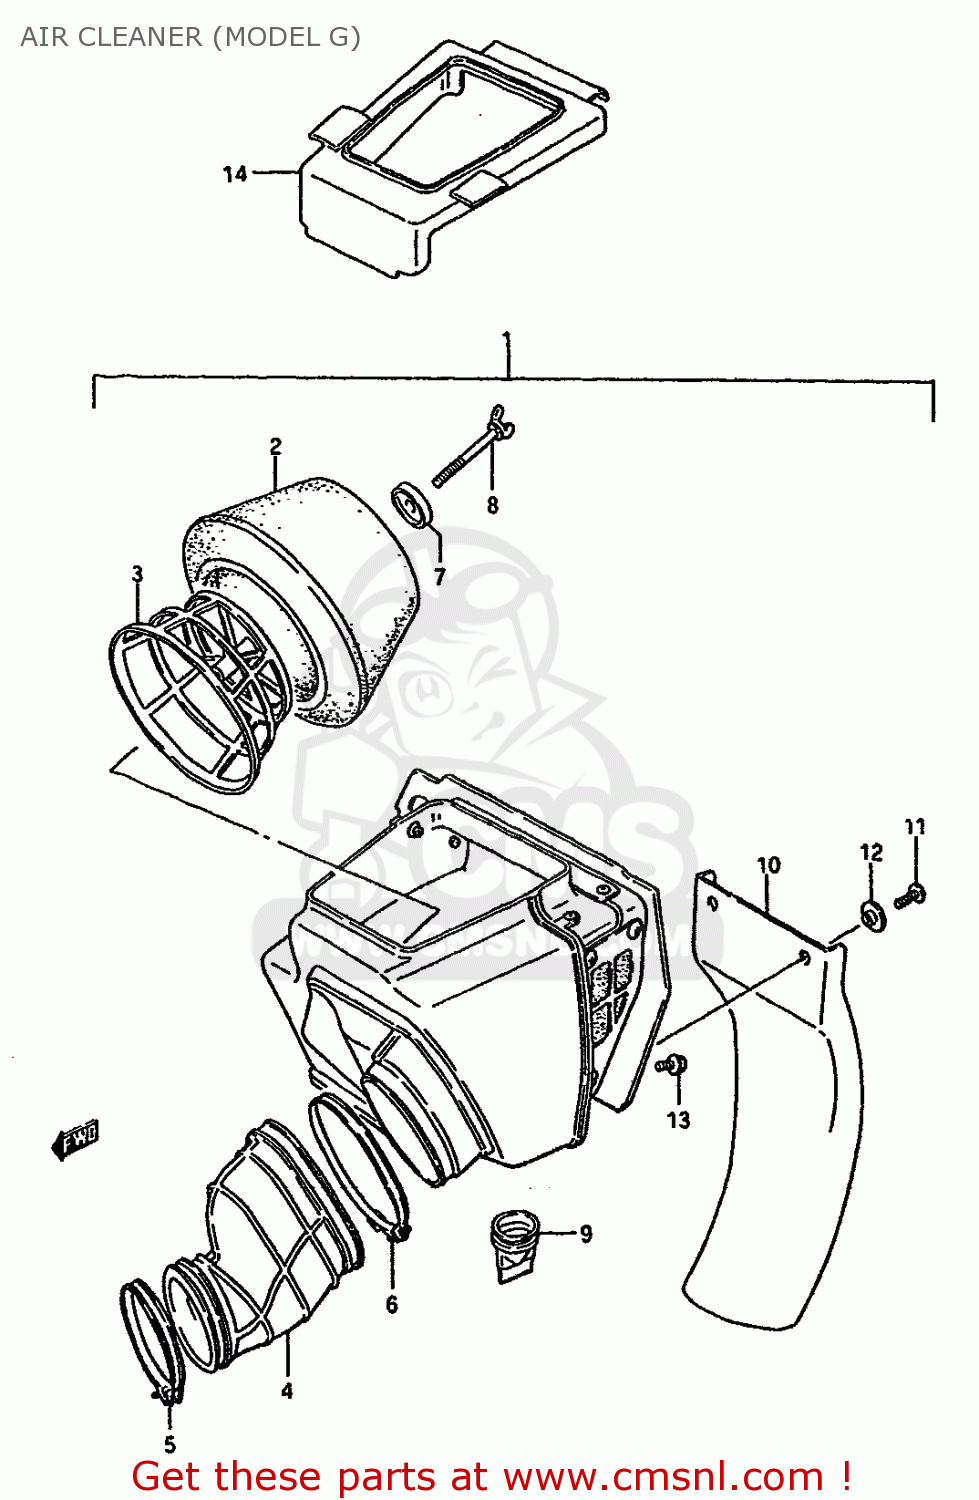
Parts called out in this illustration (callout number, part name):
1	CLEANER ASSEMBLY,AIR
2	FILTER
3	HOLDER,FILTER
4	TUBE,AIR CLEANER OUTLET
5	CLAMP
6	CLAMP
7	WASHER,AIR CLEANER
8	BOLT,WING
9	HOSE,AIR CLEANER DRAIN
10	GUARD,MUD
11	SCREW
12	COLLAR
13	BOLT
14	GUARD,MUD
